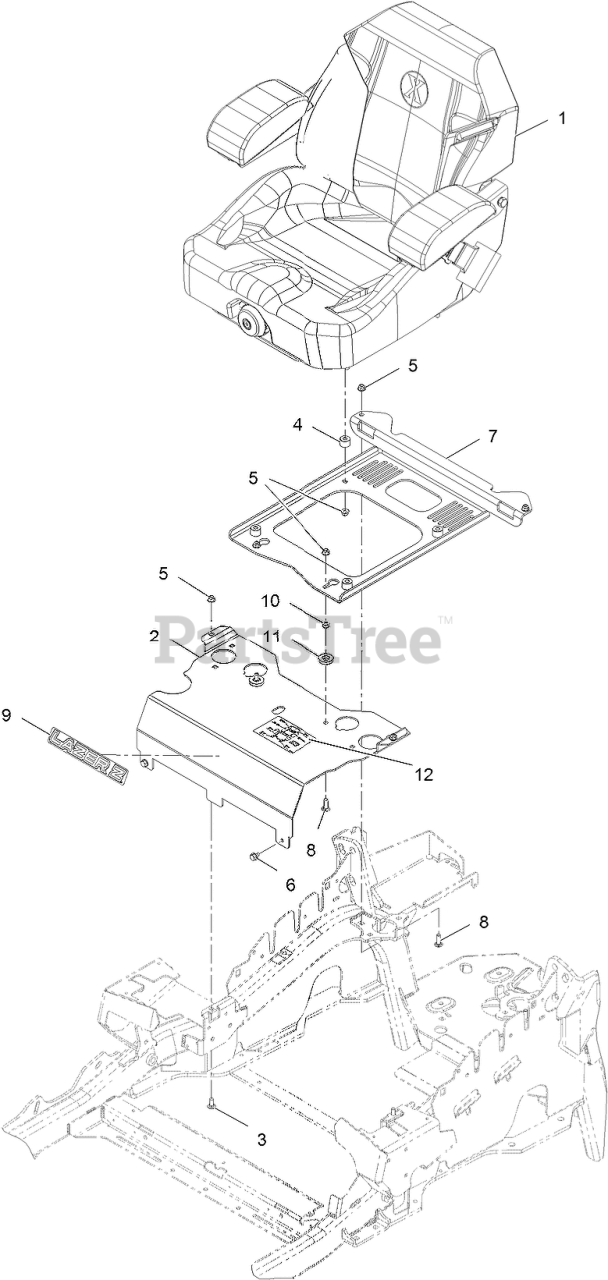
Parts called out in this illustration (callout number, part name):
1	KIT-SUSPENSION SEAT
2	Panel-Front, Seat Mount
3	SCREW-CARR
5	NUT-HF, NI
7	PLATE-SUPPORT, SEAT
8	SCREW-CARR
9	DECAL, LAZER MODEL
10	NUT-HEX
12	DECAL-SERVICE AID
